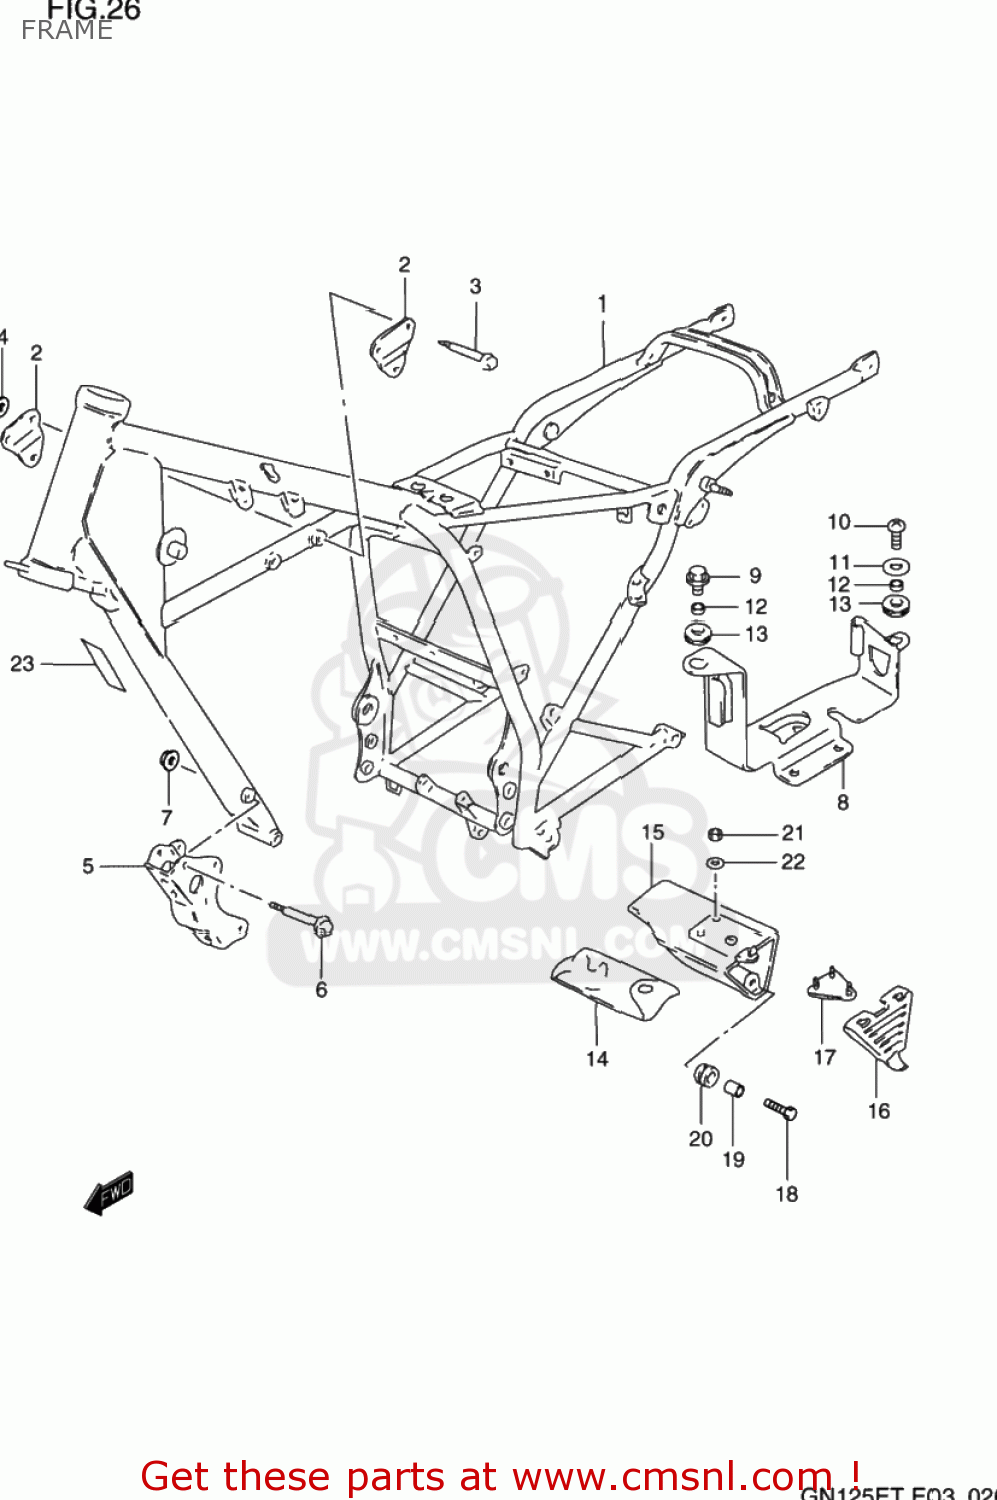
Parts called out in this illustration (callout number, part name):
1	FRAME
2	PLATE,ENGINE MOUNTING
3	BOLT(8X50)
4	NUT
5	BRACKET,ENGINE MOUNTING LWR
6	BOLT
7	NUT
8	HOLDER,BATTERY
9	BOLT 6X16
10	SCREW(6X21)
11	WASHER (6.5X20X1.2)
12	SPACER(6.1X9X7.5)
13	CUSHION
14	TOOL SET
15	BOX,TOOL
16	CAP,TOOL BOX
17	PLATE,TOOL HOLDER
18	BOLT 6X16
19	SPACER(6.1X9X7.5)
20	CUSHION
21	NUT
22	WASHER
23	LABEL
